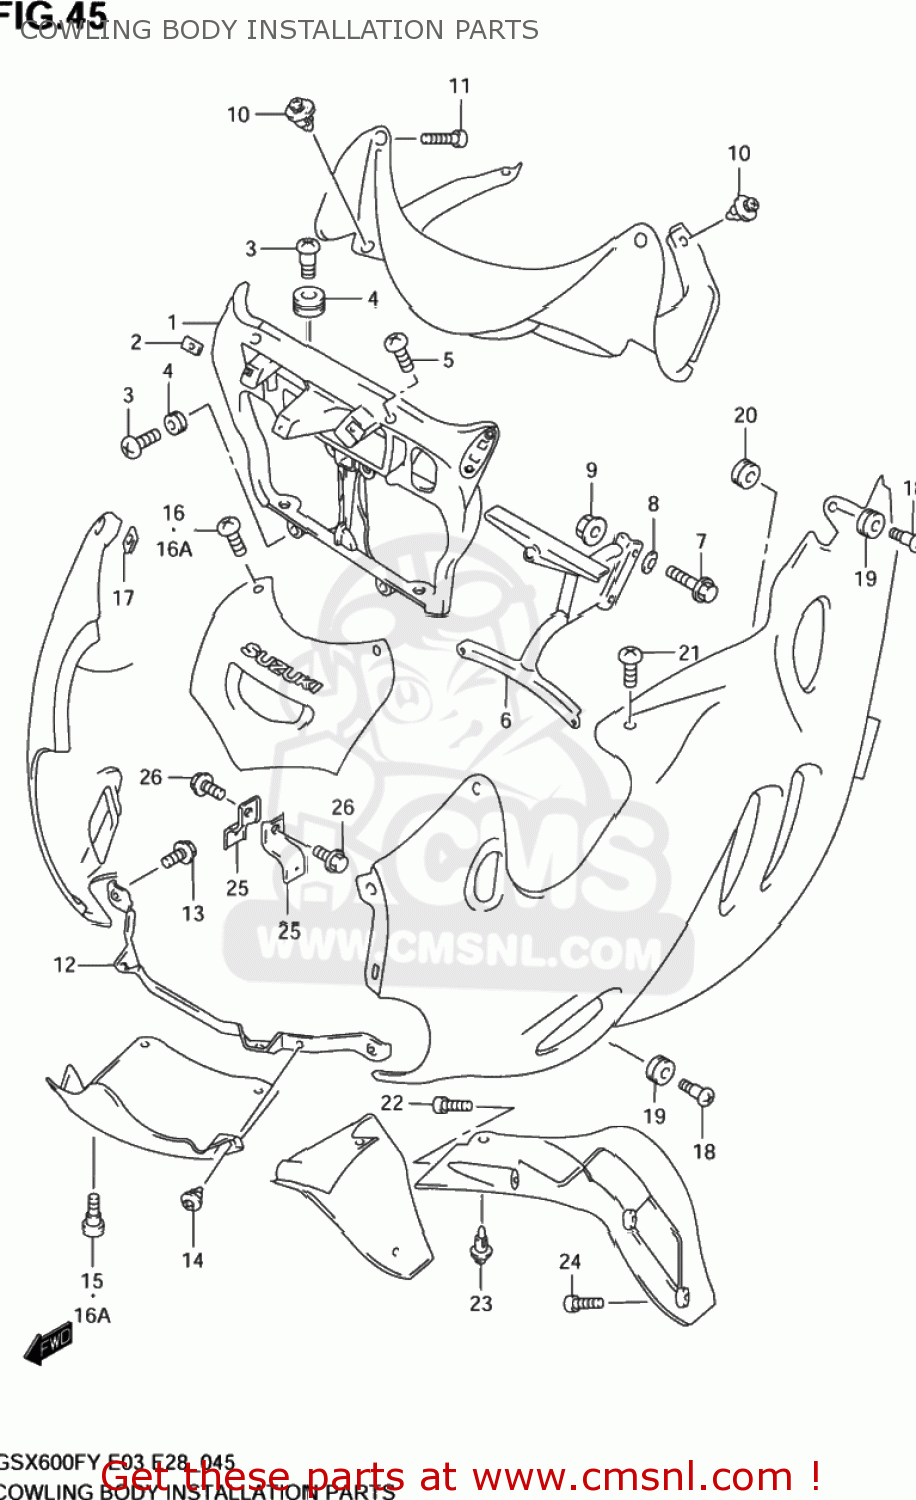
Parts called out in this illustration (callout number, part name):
1	BRACE,COWLING FR
2	NUT,COWL
3	SCREW(6X20)
4	CUSHION
5	SCREW
6	BRACE,COWLING RR
7	BOLT(8X40)
8	WASHER
9	NUT
10	CLIP(BLACK)
11	SCREW
12	BRACKET,PANEL CTR LWR
13	BOLT
14	CLIP(BLACK)
15	SCREW(5X14)
16	SCREW(5X14)
16A	SCREW(5X16)
17	NUT
18	SCREW(6X20)
19	CUSHION
20	CUSHION
21	SCREW(5X16)
22	SCREW(4X10)
23	CLIP(BLACK)
24	SCREW
25	BRACKET,COWLING SIDE LWR
26	BOLT 6X12
